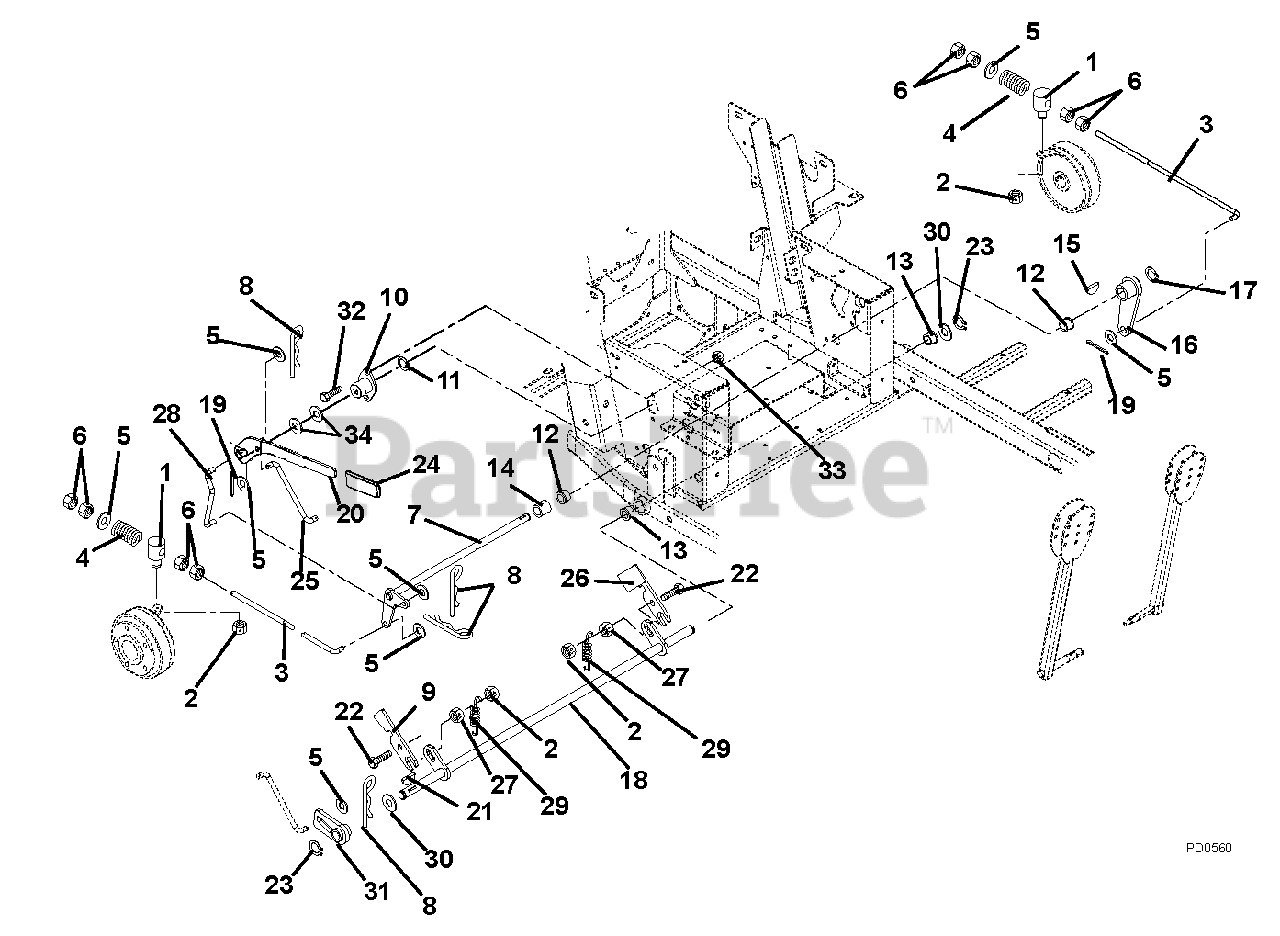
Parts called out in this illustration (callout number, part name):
1	Pivot, Brake Rod
2	Nut, Locking Center .31-18
3	PTO Link Rod
4	Spring, Compression .142 x .710 x 1.75
5	Washer, Flat Steel .406 x .812 x .065
6	Nut, Hex .38-16
7	Shaft, Brake Cross
8	Pin, Hair
9	Slide, Interlocking Brake
10	Bushing, Flange
11	Ring, Retaining External .625 x .05
12	Bushing, Flange Nylon .762 x 1.00 x .58 x 1.48
13	Bushing, Flange .515 x .75 x .745 x 1.00
14	Bushing, Sleeve .75 x 1.00 x .75
15	Key, Woodruff .19 x .75 Hard #9
16	Arm, Brake
17	Ring, Retaining External .69 x .077
18	Weldment, Mechanical Brake
19	Pin, Cotter External .09 x .75
20	Weldment, Brake Handle
21	Key, Woodruff .13 x .63
22	Bolt, Round Head Square Neck .31-18 x 1.25 Grade 5
23	Ring, Retaining External .50 x .05
24	Grip, Handle
25	Linkage, Brake Actuating
26	Interlock, Safety Switch
27	Nut, Locking Top Flange .31-18
28	Linkage, Brake Actuating
29	Spring, Tension .048 x .44 x 1.75
30	Washer, Flat Steel .505 x 1.00 x .062
31	Weldment, Parking Brake Hub
32	Bolt, Hex .31-18 x .75 Grade 5
33	Nut, Locking Top Flange .31-18
34	Washer, Flat Steel .630 x 1.25 x .062
